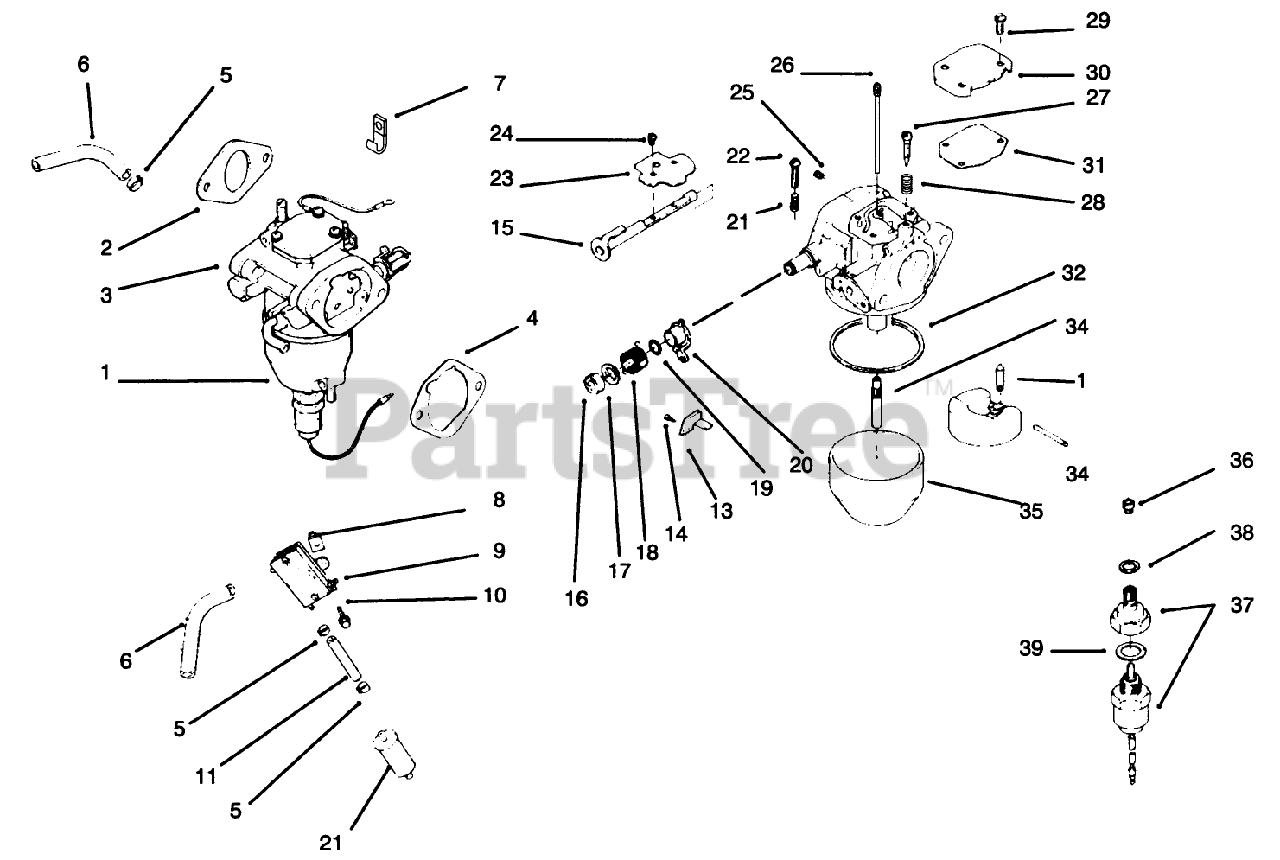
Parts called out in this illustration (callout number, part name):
1	Kit-Carburetor (Incl. Ref.#2-4)
2	Gasket-Carburetor (Only On: 72103)
3	Carburetor (Ref. Only) (Inc. Ref.15-39)
4	Gasket-A/C Base (Only On: 72103, 72083)
5	Clamp
6	Line-Fuel 12" (Only On: 72103)
7	Clip-Cable (Only On: 72103)
9	Pump-Fuel
11	Line-Fuel 10 1/2" (Only On: 72103, 72083)
12	Filter-Fuel
13	Bracket-Throttle Stop (Only On: 72103, 72083)
14	Screw M2.5X45X5.5 (Only On: 72103)
15	Shaft-Choke (Only On: 72103, 72083)
16	Washer (Only On: 72103, 72083)
17	Collar-Choke (Only On: 72103, 72083)
18	Spring-Choke Return (Only On: 72103, 72083)
19	Ring-Choke Lever (Only On: 72103)
20	Lever-Choke (Only On: 72103)
21	Spring-Throttle Screw (Only On: 72103, 72083)
22	Screw-Throttle Adjust (Only On: 72103, 72083)
23	Valve-Choke (Only On: 72103)
24	Screw-Throttle Shaft (Only On: 72103, 72083)
25	Jet-Air Bleed (Only On: 72103)
26	Jet-Slow (Only On: 72103)
27	Screw-Idle Adjust (Only On: 72103, 72083)
28	Spring-Idle Adjust Screw (Only On: 72103)
29	Screw (Only On: 72103)
30	Cover-Passage (Only On: 72103, 72083)
31	Gasket-Passage Cover (Only On: 72103, 72083)
32	Gasket-Float Chamber (Only On: 72103)
33	Kit-Float Repair (Only On: 72103)
34	Nozzle-Main (Only On: 72103,72083)
35	Chamber-Float (Only On: 72103)
36	Jet-Main (Only On: 72103)
37	Kit-Solenoid INC 41-42 (Only On: 72103, 72083)
38	Gasket-Chamber Screw (Only On: 72103)
39	Gasket-Solenoid (Only On: 72103, 72083)
